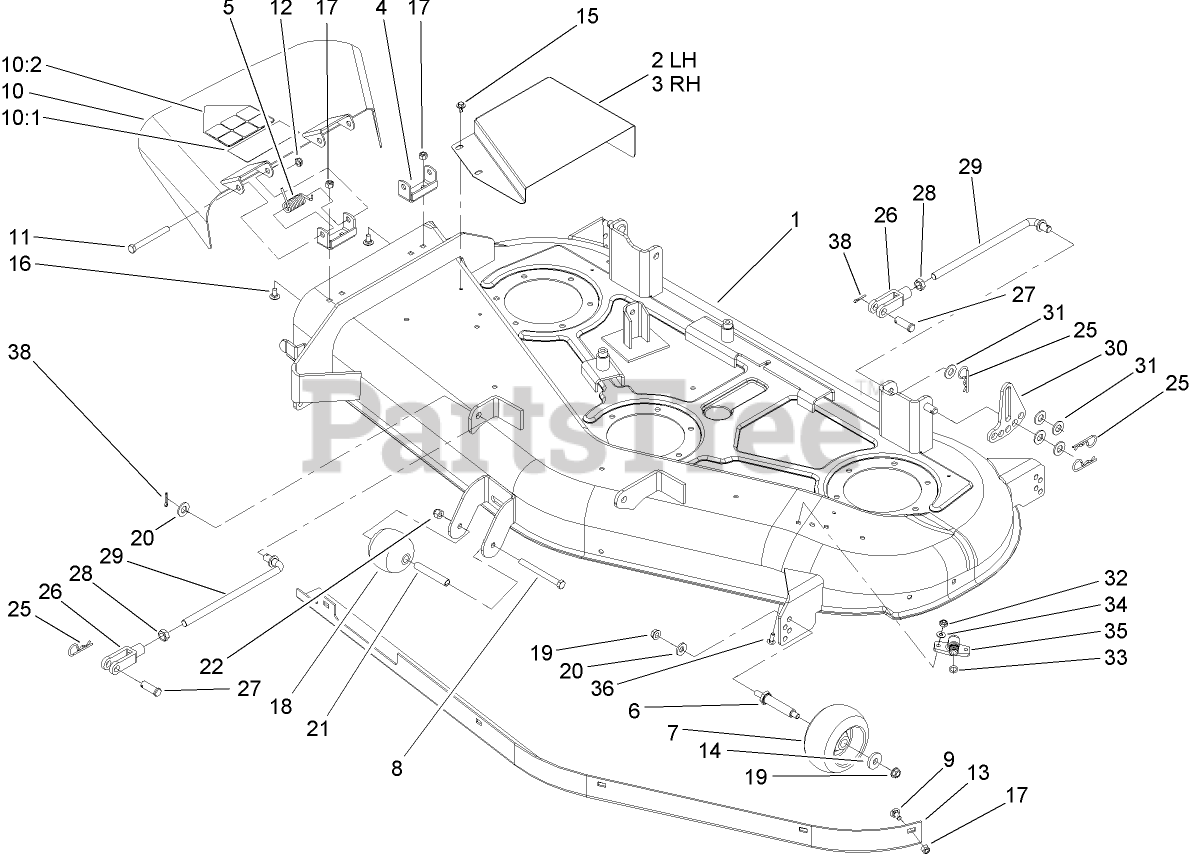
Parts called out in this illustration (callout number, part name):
2	COVER-BELT, LH
3	COVER-BELT, RH
4	BRACKET-PIVOT
5	SPRING
7	ROLLER-SCALP, ANTI
8	SCREW-HH
9	SCREW-CARR
10:1	DECAL-DANGER
10:2	DECAL-DANGER
11	SCREW-HH
12	NUT-HEX
14	WASHER
15	SCREW-HHFTF
16	SCREW-CARR
17	NUT-LOCK, NI
18	ROLLER
19	NUT-HHF, WHIZ
20	WASHER-BELLEVILLE
21	TUBE-SPACER, WHEEL
22	NUT-LOCK, NI
25	PIN-COTTER
26	CLEVIS
27	PIN-CLEVIS
28	NUT-JAM
30	LINK-HOC, ADJUSTING
31	WASHER-FLAT
32	NUT-LOCK, NI
33	O-RING
34	WASHER-FLAT
36	BOLT-CARR
38	PIN-COTTER
